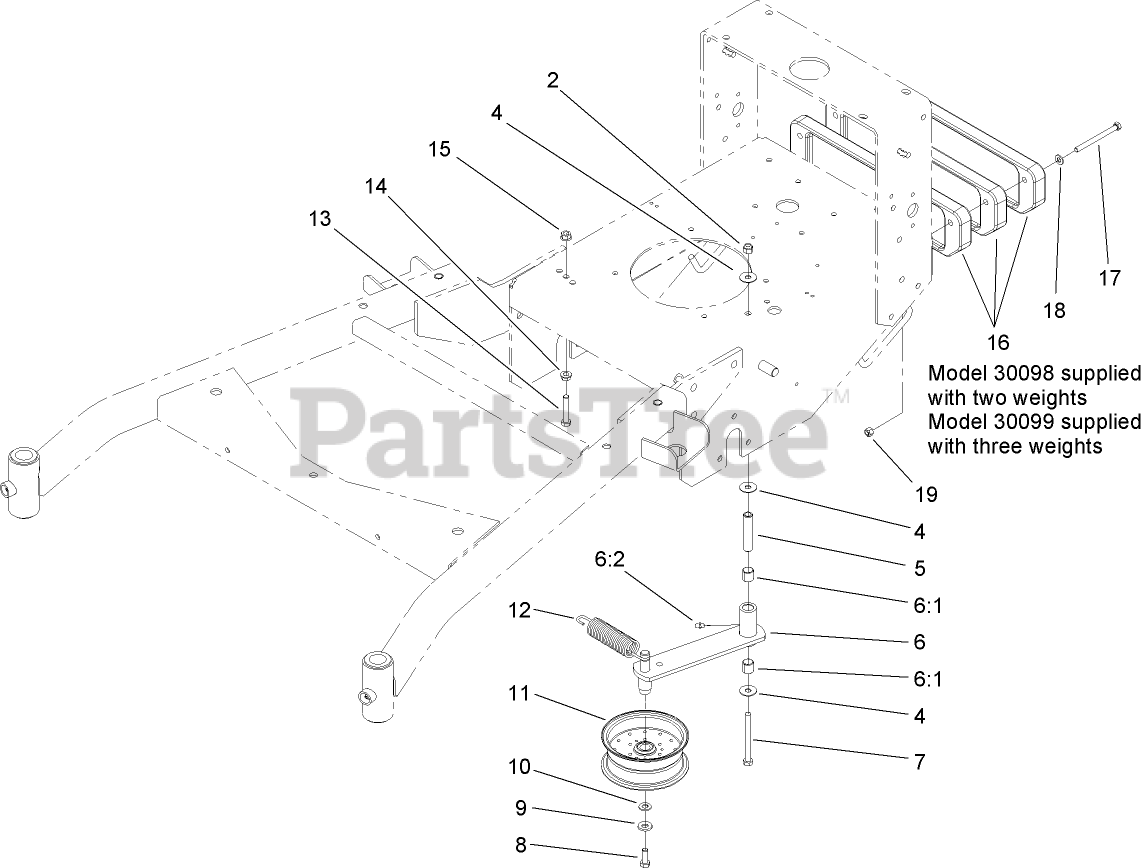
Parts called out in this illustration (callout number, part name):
2	NUT-LOCK, NI
4	WASHER
5	TUBE-IDLER
6	IDLER ARM ASM
6:1	SLEEVE-BEARING
6:2	FITTING-GREASE
7	SCREW-HH
8	SCREW-HH
9	WASHER-BELLEVILLE
10	WASHER-FLAT
11	PULLEY-IDLER
12	SPRING-EXTENSION
13	SCREW-HH
14	NUT-HHF, WHIZ
15	NUT-HF
16	WEIGHT-CAST
17	SCREW-HH
18	WASHER-PLAIN
19	NUT-LOCK, NI
